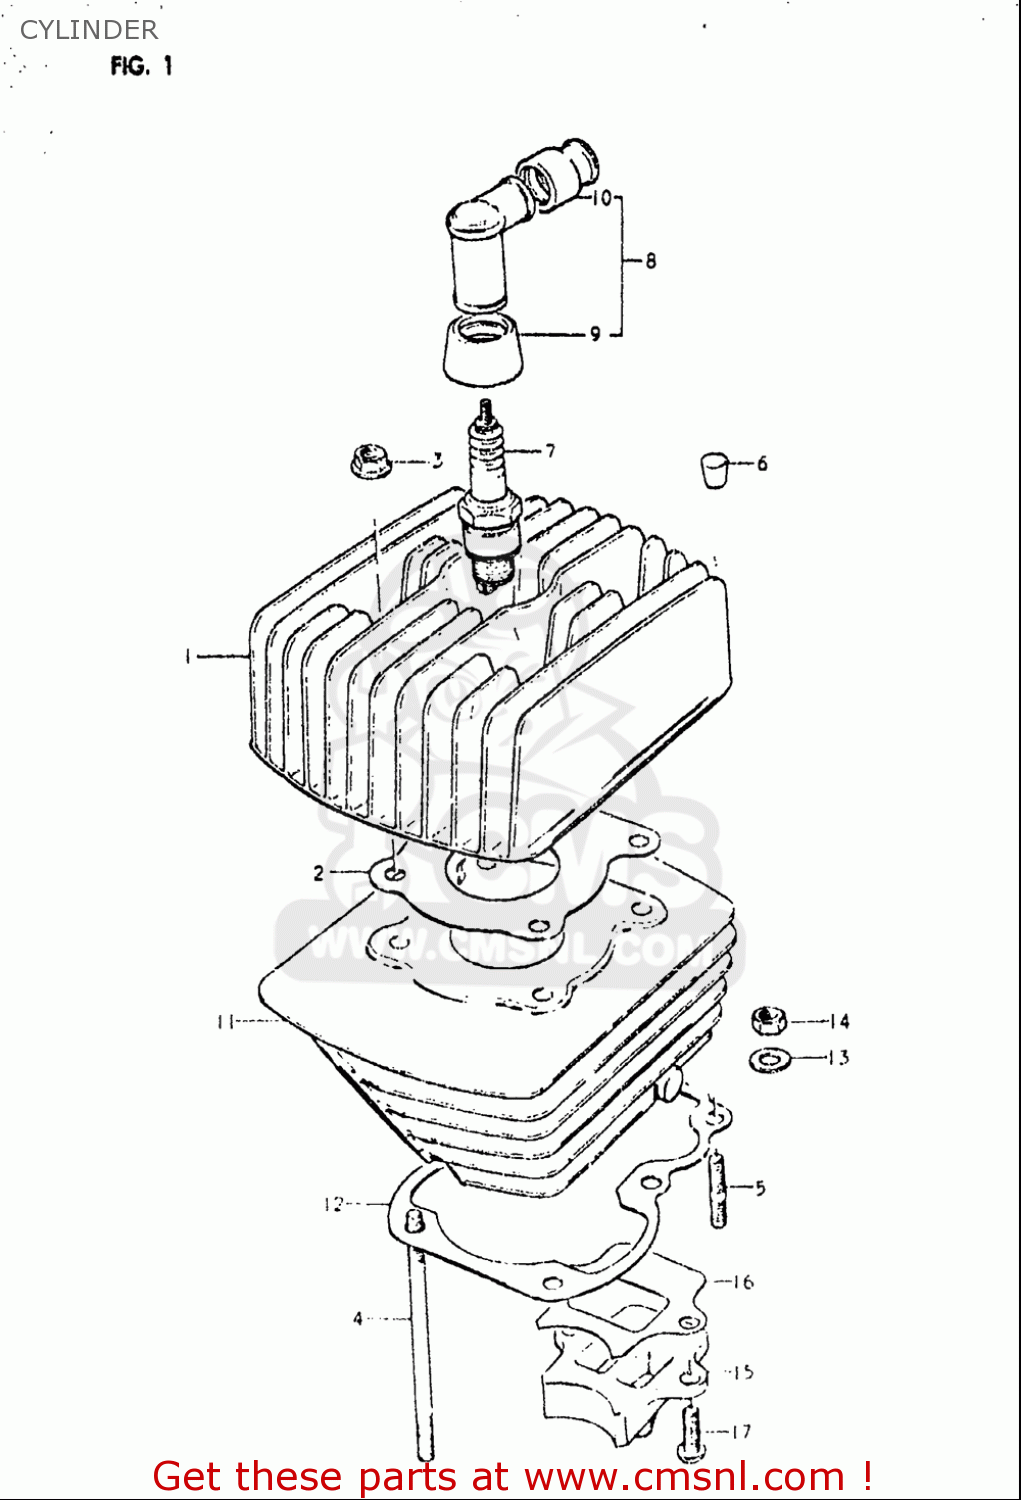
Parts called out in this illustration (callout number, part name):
2	GASKET,CYLINDER HEAD (NAS)
3	NUT
4	BOLT,STUD
5	BOLT,STUD
6	PAD,CYLINDER HEAD
7	SPARK PLUG
8	CAP,SPARK PLUG
9	SEAL,SPARK PLUG
10	SEAL,HIGH TENSION CORD
11	CYLINDER
12	GASKET,CYLINDER (NAS)
13	WASHER
14	NUT
15	VALVE ASSY,REED
16	GASKET,REED VALVE (NAS)
17	SCREW
